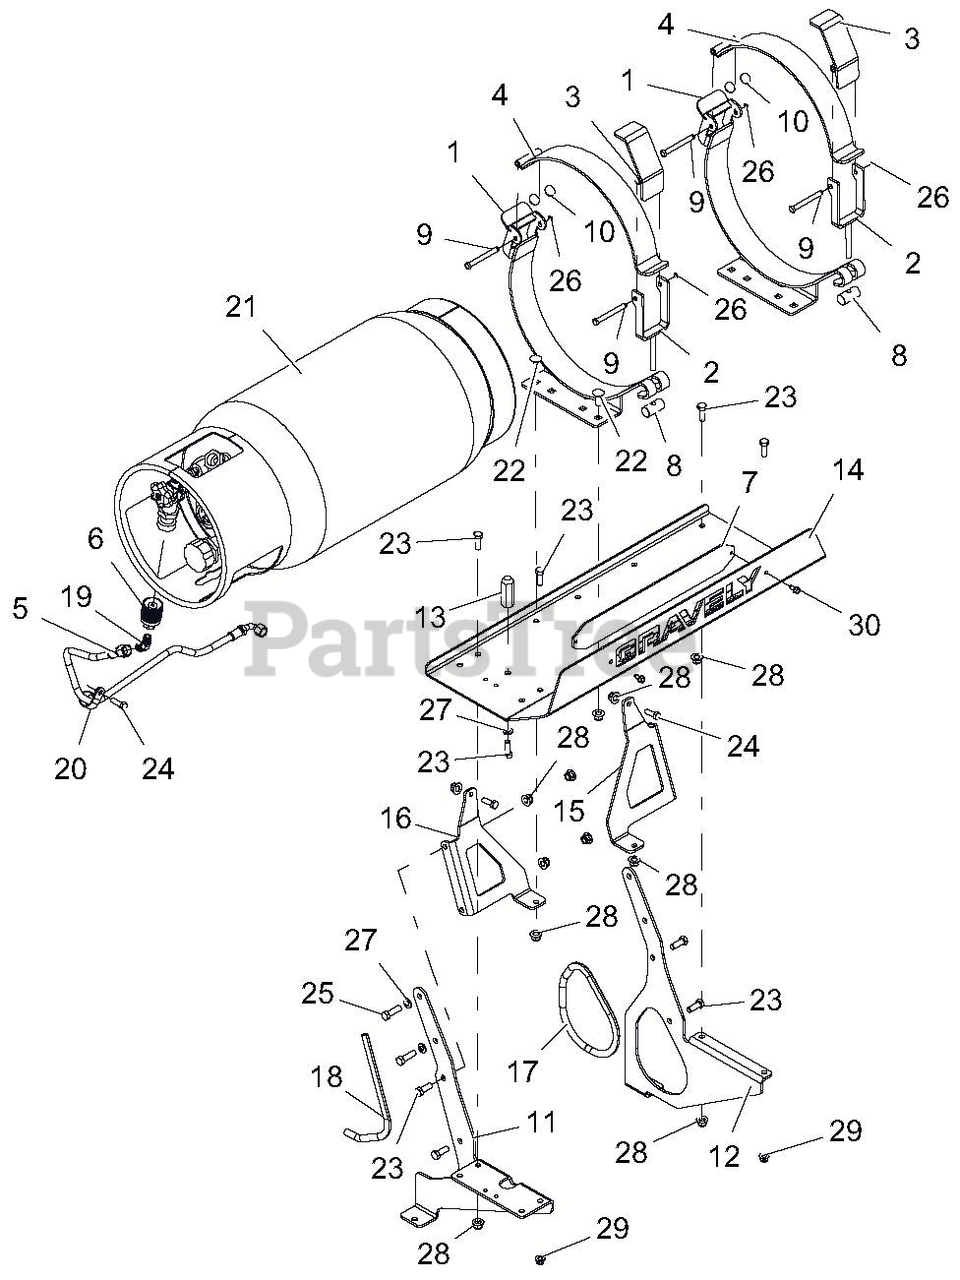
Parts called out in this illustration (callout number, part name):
1	WLDMT, CLAMP LP TANK
2	WLDMT, TANK CLAMP TOGGLE
3	WLDMT, TANK TOGGLE HANDLE
4	WLDMT, UPPER LP TANK CLAMP
5	HOSE, LPG SS25UL 6-4-6-30.00
6	FTG, LPG TANK COUPLER -LH THRD
7	PLATE, BACK NAME
8	PIVOT, LP CLAMP HANDLE
9	PIN, LP CLAMP
10	MAGNET, .75X.060, LP CLAMP
11	EAR, MOUNT RH
12	EAR, MOUNT LH
13	POST, INDICATOR LP TANK
14	SUPPORT, TANK PROPANE
15	BRACE, OPERATOR LH
16	BRACE, OPERATOR RH
17	TRIM, RUBBER EDGE 17.75"
18	TRIM, RUBBER EDGE 11.75"
19	FTG, 45° 1/4-NPTF 9/16-18 45 FLG
20	CLAMP, CUSHIONED STEEL REV
21	TANK, LP, 33.5 LB VAPOR L&G
22	BLT-RDHDSQNK .38-16X1.00 G5 YWZC
23	BLT-HEX .38-16X1.00 GR5 YWZC
24	BLT-HEX .31-18X1.00 GR5 YWZC
25	BLT-HEX .38-16X1.25 GR5 YWZC
26	RG-RTNG-EXT .312X.025
27	WSHR-LK .38X.094 REG YWZC
28	NUT-LK-NYL-FLG .38-16 YWZC
29	NUT-LK-NYL-FLG .31-18 YWZC
30	SCR-TAP .25-20X.50 HWH TR YWZ
